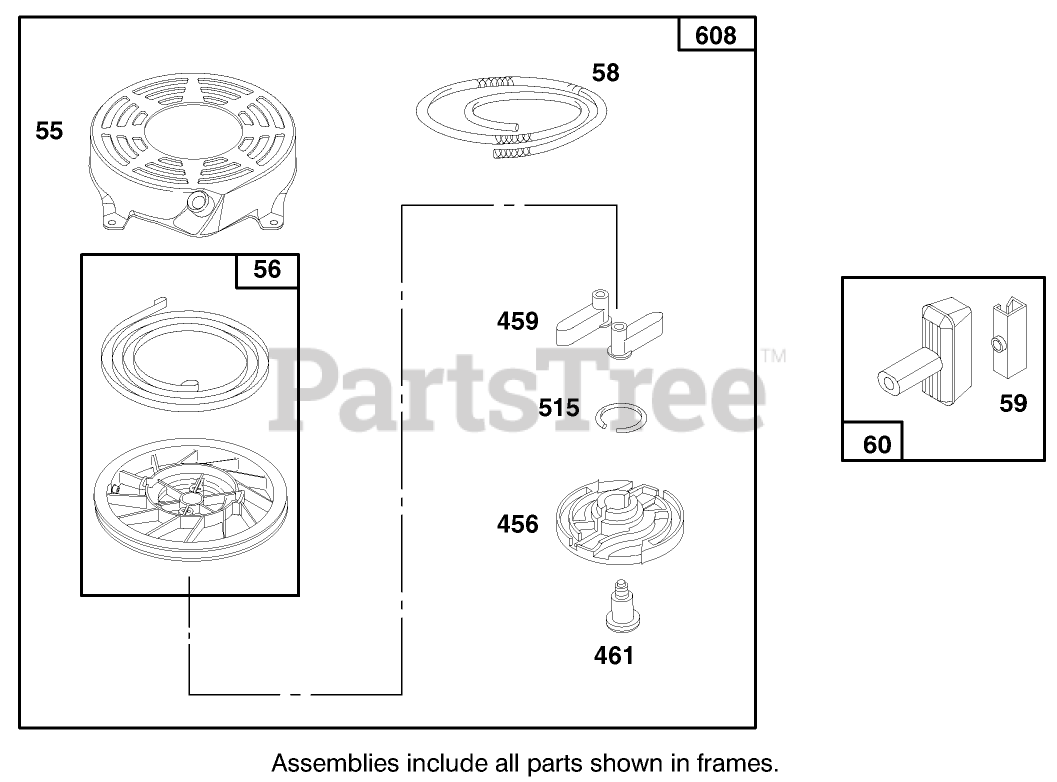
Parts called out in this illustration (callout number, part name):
55	Rewind StarterHousing
56	Pulley and Spring ASM
58	Rope?Starter (Cut to Required Length)
59	Insert-Starter Grip
60	Handle-Rewind Starter
456	Retainer-Spring
459	Ratchet-Pawl
461	Pin-Starter
515	Spring-Torsion
608	Starter-Rewind
